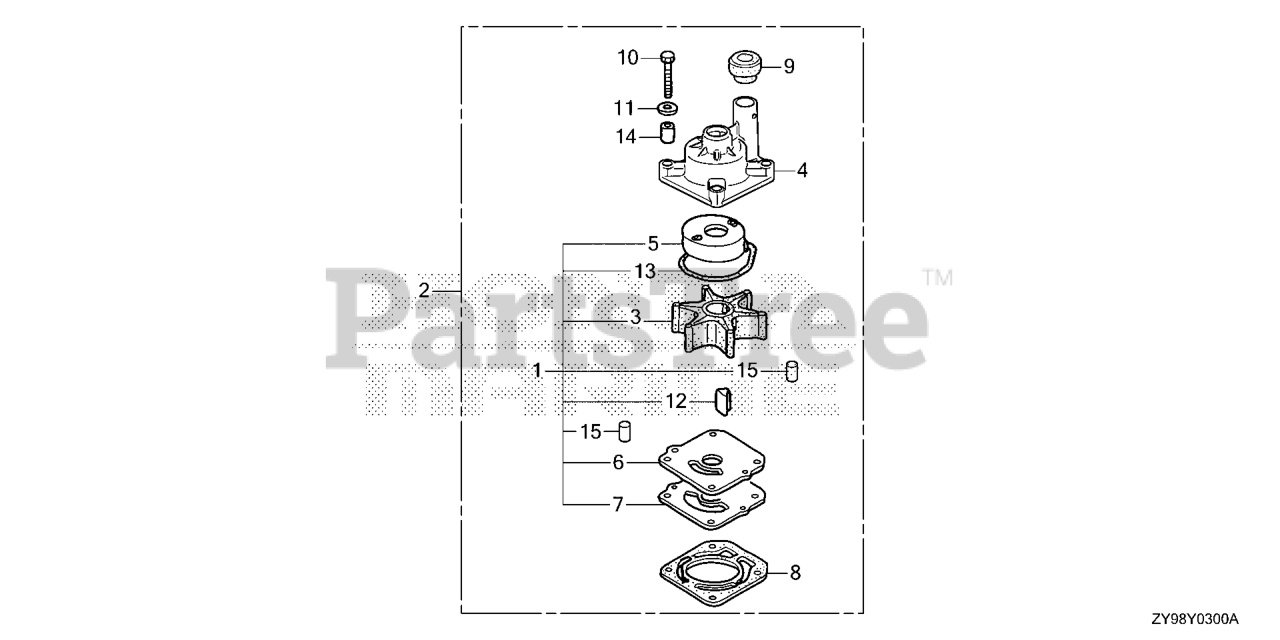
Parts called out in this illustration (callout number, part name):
1	PUMP KIT, IMPELLER
2	PUMP KIT, IMPELLER
3	IMPELLER, PUMP
4	HOUSING, IMPELLER
5	LINER, PUMP
6	COVER, IMPELLER
7	GASKET B, IMPELLER
8	GASKET, WATER PUMP
9	RING, WATER TUBE SEAL
10	BOLT, HEX. (8X55)
11	WASHER (8MM)
12	KEY, WOODRUFF
13	O-RING, WATER PUMP
14	COLLAR, DISTANCE
15	PIN, DOWEL (6X10)
